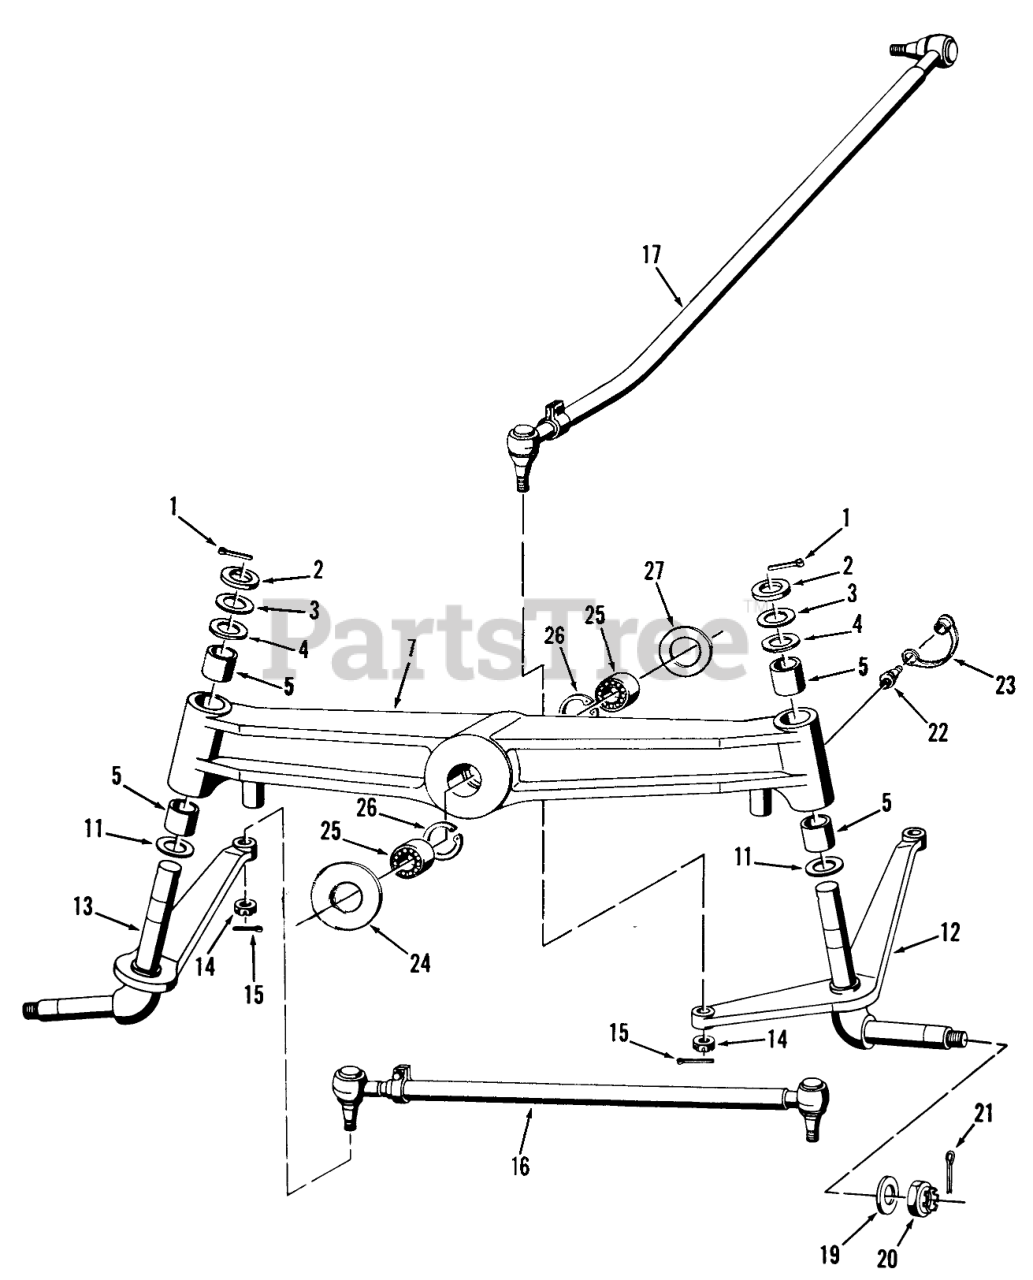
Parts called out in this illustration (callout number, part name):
2	Washer
3	Shim (22 X 32 0.3 DIN 988)
3	Shim (22 X 32 0.5 DIN 988)
5	Sleeve
7	Front Axle Assy. (with Parts 5, 11, 22, 23, 25 and 26)
11	Washer
12	Steering Knuckle Spindle Left Assy.
13	Steering Knuckle Spindle Right Assy.
14	Castet Nut
16	Tie Rod (Consisting of Parts 14, 15 and 16)
17	Thrust Rod (Consisting of Parts 14, 15 and 17)
19	Washer
20	Castel Nut
22	Grease Fitting
24	Washer
25	BALL BEARING
26	Circlip
27	WASHER
